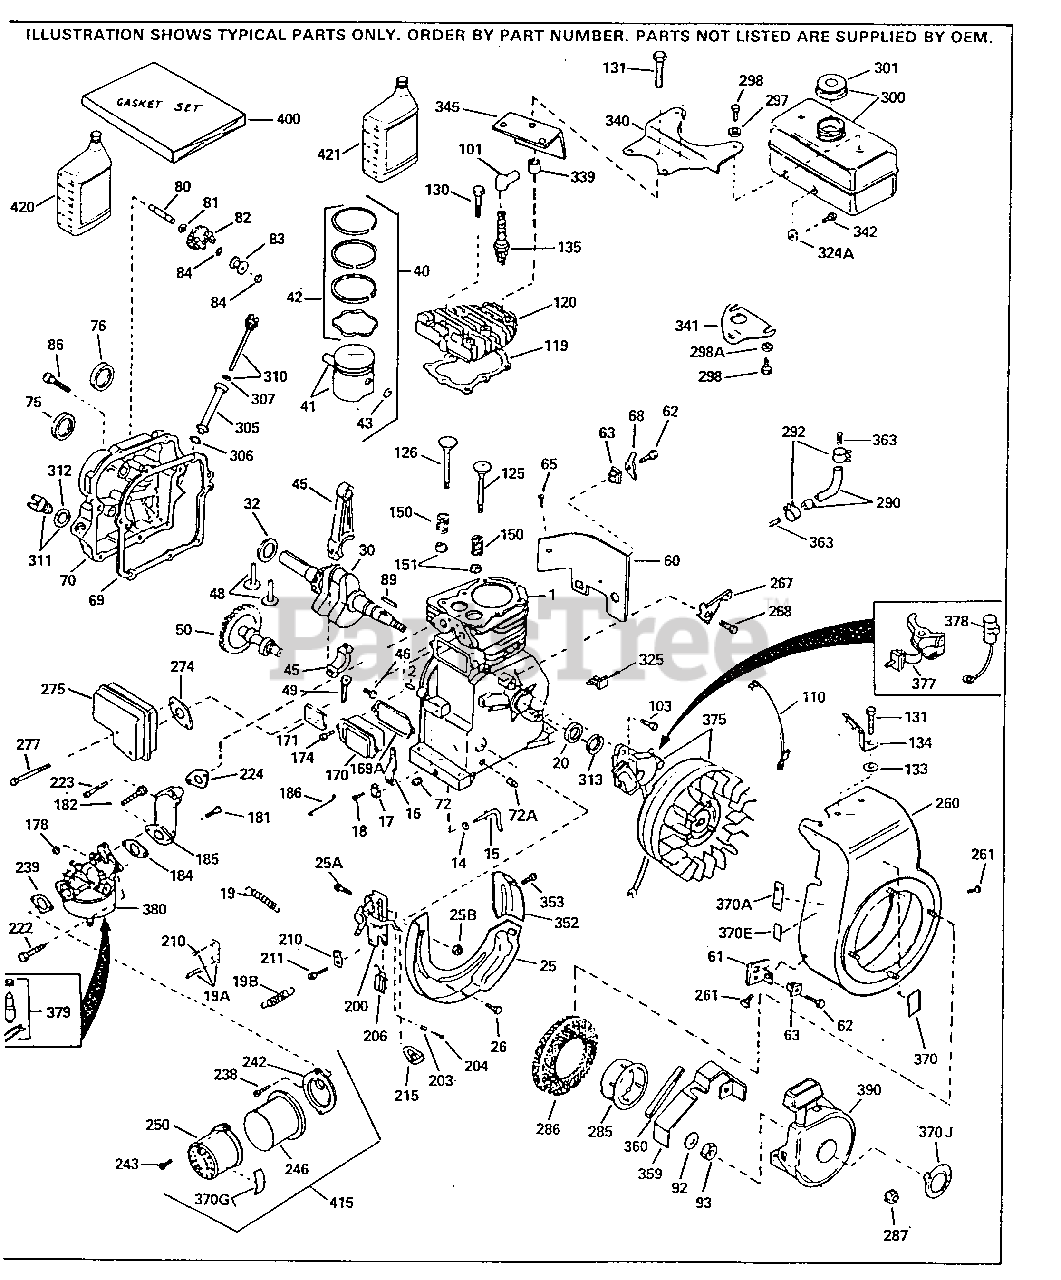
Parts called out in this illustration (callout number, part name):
1	"Cylinder (Incl. 2,20,72 & 72) 2-5/8" Bore
2	Dowel Pin
14	Flat Washer
15	Rod, Governor
16	Lever, Governor
17	Clamp, Governor lever
18	Screw, 8-32 x 5/16"
19	Spring, Extension
20	Seal, Oil
25	Baffle, Blower housing
25A	Screw, 8-32 x 1/2"
25B	Lock Nut, 8-32
26	Screw, 1/4-20 x 5/8"
30	Crankshaft
32	Washer, Thrust NOTE: This thrust wash er maynot be required if a new cranks hafthas been installed. Check the pro per Mechanic's Handbook for acceptabl e end play. Use this .010" thrust was her if excess end play is measured.
40	Piston, Pin & Ring Set (Std.)
40	Piston, Pin & Ring Set (.010" OS)
40	Piston, Pin & Ring Set (.020" OS)
41	Piston & Pin Ass'y. (Std.) (Incl. 43)
41	Piston & Pin Ass'y. (.010" OS) Incl. 43
41	Piston & Pin Ass'y. (.020" OS) Incl. 43
42	Ring Set (Std.)
42	Ring Set (.010" OS)
42	Ring Set (.020" OS)
43	Piston Pin Retaining Ring
45	Rod Assy., Connecting (Incl. 46 & 49)
46	Bolt, Connecting rod
48	Valve Lifter
49	Dipper, Oil
50	Camshaft (Extended)
60	Blower Housing Extension
61	Bracket, Grommet mounting
62	Screw, 8-32 x 3/8"
63	Breather Tube Grommet
65	Screw, 10-24 x 1/2"
69	* Gasket, Cylinder cover
70	Cover, Cylinder (Incl. 75, 76 & 80)
72	Oil Drain Plug (Sq. hd., 1/4-18)
75	Oil Seal
76	Camshaft Seal
80	Shaft, Mechanical governor
81	Washer, Flat
82	Gear, Governor (Incl. 81)
83	Spool, Governor
84	Retaining Ring
86	Screw, 1/4-20 x 1-1/4"
89	Key, Flywheel
92	Washer, Belleville
93	Nut, Flywheel
101	Cover, Spark plug
103	Screw, 1/4-20 x 5/8"
110	Wire, Ground
119	* Gasket, Cylinder cover
120	Head, Cylinder (Incl. 131)
125	Exhaust Valve (Std.) (Incl. 151)
125	Exhaust Valve (1/32" OS) (Incl. 151)
126	Intake Valve (Std.) (Incl. 151)
126	Intake Valve (1/32" OS) (Incl. 151)
130	Screw, 5/16-18 x 1-1/2"
131	Screw, 5/16-18 x 2"
135	Resistor Spark Plug - RJ17LM
150	Spring, Valve
151	Cap, Valve spring
169A	* Gasket, Breather
170	Breather Assy. (Incl. 169A & 171)
171	Element, Valve body
174	Screw, 10-24 x 1/2"
178	Nut & Lock Washer 1/4-28
181	Screw, 1/4-28 x 7/8"
182	Screw, 1/4-28 x 2"
184	* Gasket, Carburetor
185	Pipe, Intake
186	Link, Governor-to-throttle
186	Link, Throttle
200	Control Bracket (Incl. 25A,25B,203,20 4 & 206) NOTE: In original production the speed control assembly is riveted to the blower housing baffle (33342) . Replacement speed control includes screws (650139) and nuts (30322) for mounting. Replacement baf
203	Spring, Compression
204	Screw, 5-40 x 7/16"
206	Terminal Ass'y. (Use as required)
215	Knob, Speed control
222	Screw, 10-32 x 1/2"
223	Screw, 1/4-20 x 1-19/32"
224	* Gasket, Intake
238	Screw, 10-32 x 1/2"
260	Housing, Blower (For electric starter ) NOTE: Replacement hardware m ay differ when servicing starter assy . or blower housing. Refer to Service Bulletin 508.
261	Screw, 1/4-28 x 7/16"
267	Bracket, Hold down
268	Screw, 10-24 x 9/16"
274	* Gasket, Exhaust
275	Muffler (Incl. 274)
277	Screw, 1/4-20 x 2-1/2" Use as requir ed
277	Screw, 1/4-20 x 5/8" Use as required
277	Screw, 1/4-20 x 2-3/8" Use as requir ed
277	Screw, 1/4-20 x 2-1/4" Use as requir ed
285	Cup, Starter
286	Screen, Starter cup
287	Nut & Lock Washer 1/4-28
290	Fuel Line (8.62") as req.)
290	Fuel Line (Braided 16")(40 cm) Use as req.
290	Line, Fuel (Braided 32")(81 cm) Use a s req.
292	Fuel Line Clamp
298	Screw, 1/4-15 x 7/8"
300	Fuel Tank (Incl. 292 & 301) NOTE: The se tanks were builtwith different siz e fuel inlet openings. Tanks with the 1-3/16" I.D. opening use fuel cap 34 210. Tanks with the 1-1/2" I.D. openi ng use fuel cap 35355.
301	Fuel Cap (Red 1-1/2" ID) also availab le in Packaged Part #740005B
301	Fuel Cap (use as required)
301	Fuel Cap (Red)
305	Tube, Oil fill
307	"O" Ring
310	Dipstick, Oil (Incl. 307)
313	Gasket, Stator
325	Wire Clip
340	Fuel Tank Bracket
341	Fuel Tank Bracket
342	Screw, T-30, 1/4-20 x 1/2" as req.)
342	Screw, 1/4-20 x 5/8" Use as required
342	Screw, 1/4-20 x 7/16" Use as require d
342	Screw, 1/4-20 x 11/16" Use as requir ed
345	Baffle, Heat
352	Extension, Baffle
353	Screw, 8-32 x 1/2"
359	Guard, Starter
360	Seal, Snow guard
370A	Decal, Instruction
375	Magneto (w/ring gear) The complete ma gneto is not available as an assembly . The magneto number is shown for ref erence purpose only.Order component p arts individually, as shown in parts list. (Refer to Division 5, Section B , page 35 or Fiche 14A,
377	Breaker Points (also available in Pac kaged Part #740037B)
378	Condenser (also available in Packaged Part #740037B)
379	Inlet Needle, Seat & Clip Assy.
380	Carburetor (Incl. 184) (Similar to 63 2113A except has no bowl drain. Refer to Division 5, Section A, page A1-2 or Fiche 14A, Grid E-1, for breakdown )
390	Rewind Starter Replacement hardware m ay differ when servicing starter asse mbly or blower housing. Refer to Ser vice Bulletin 508. (Refer to Division 5, Section C, page 29 or Fiche 14A, Grid G-8, for breakdown)
400	Gasket Set (Incl. items marked*)
415	Air Cleaner Ass'y. (Incl. 233, 238, 2 39, 243, 246, 250 & 370G) (Use as req uired)
420	SAE 30 4-Cycle Engine Oil (Quart)
421	SAE 5W30 4-Cycle Engine Oil - Quart - Winter
